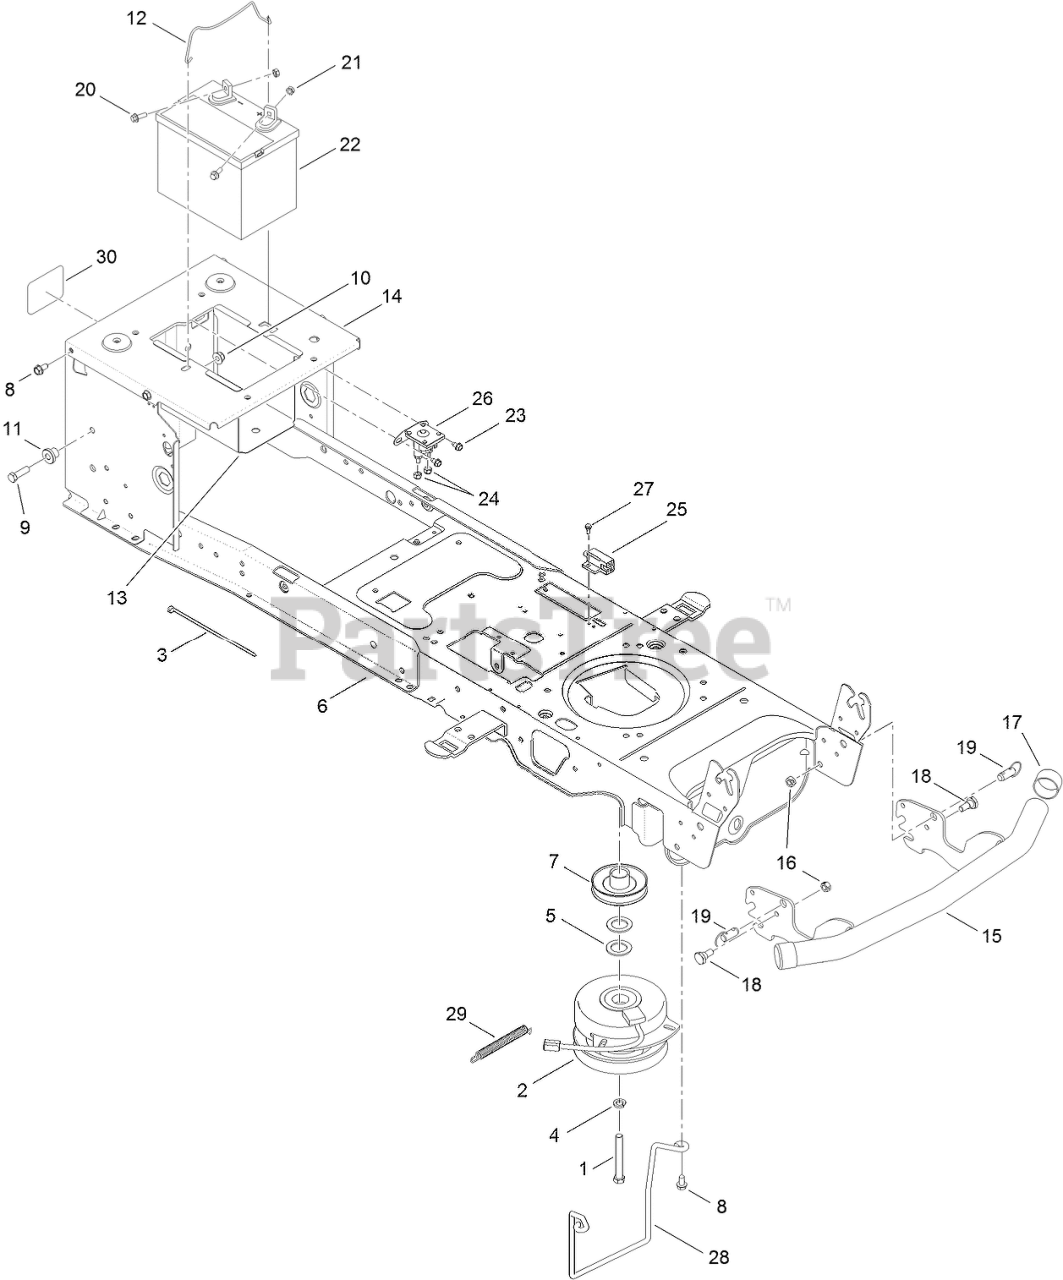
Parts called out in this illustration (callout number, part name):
1	SCREW-HH
2	CLUTCH-ELECTRIC
3	TIE-CABLE
4	WASHER-LOCK
5	WASHER-FLAT
6	LOWER FRAME ASM
7	PULLEY-ENGINE
8	SCREW-TAP
9	SCREW-HH
10	NUT-LOCK, FLANGE
11	SPACER-SHOULDER
12	ROD-HOLDDOWN, BATTERY
13	TRAY-BATTERY
14	BRACKET-FRAME, SEAT
15	BUMPER-UNIVERSAL
16	NUT-LOCK
17	CAP-HUB
18	BOLT-SHOULDER
19	PIN-RELEASE, QUICK
21	NUT-SEMS
22	BATTERY-245, CCA (DRY FLAT TOP)
23	SCREW-TAP
24	NUT-LOCK, FLANGE
25	SWITCH-INTERLOCK, NO/NC
26	SOLENOID-12V, 2 POST 2 Tab
27	BOLT-SHOULDER
28	ROD-KEEPER, BELT
29	SPRING-EXTENSION
30	DECAL-RELEASE, HYDRO
